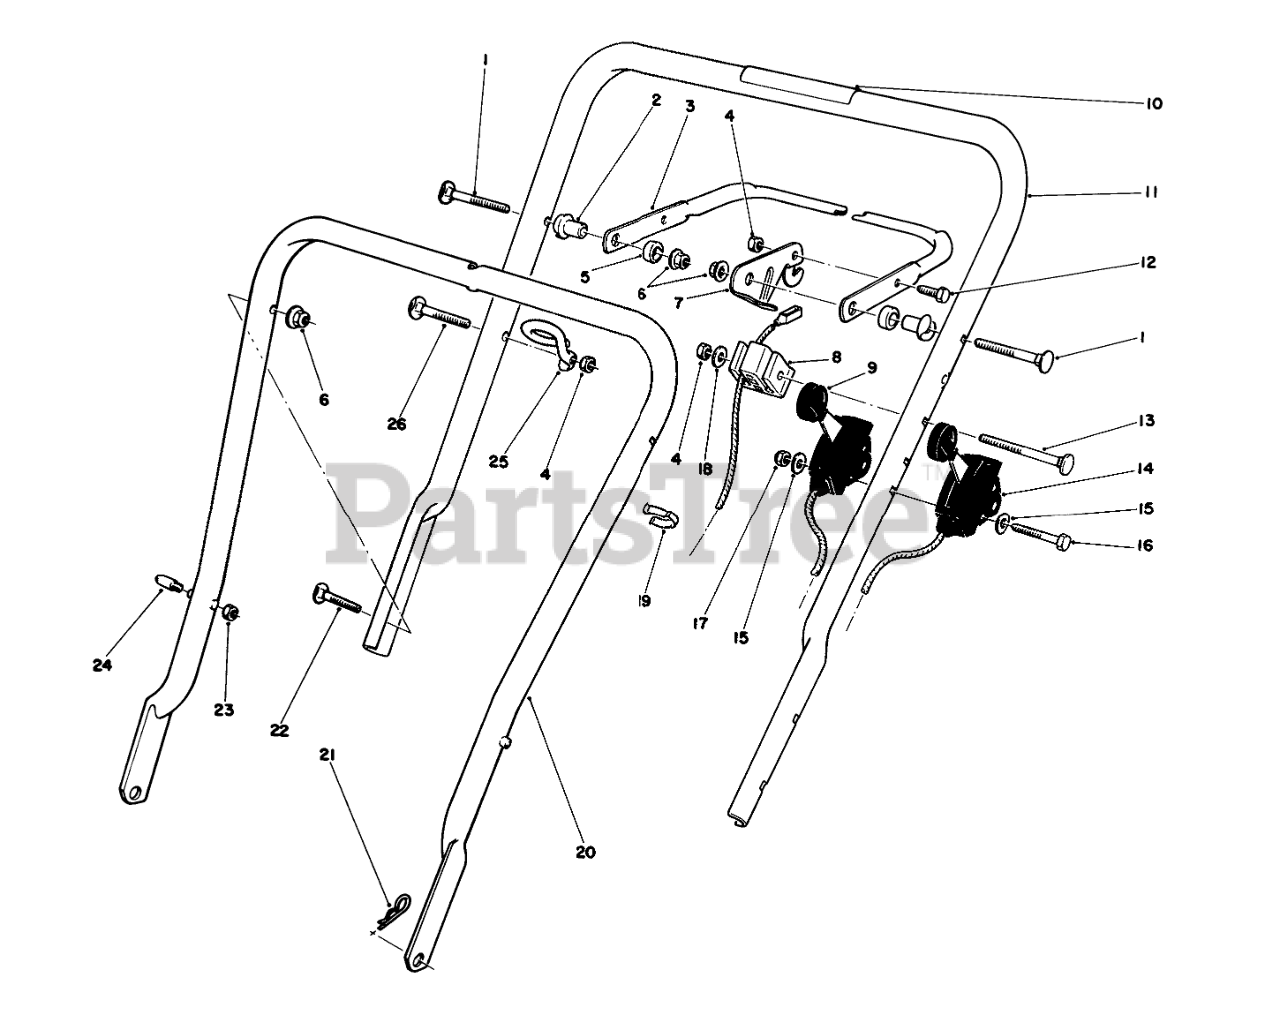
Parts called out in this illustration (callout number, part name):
1	5/16-18 X 2 HNDLE SCREW
2	SPACER-SUPPORT
3	CONTROL BAR PROMO
4	NUT-LOCK, NI
5	SPACER-NYLON
6	NUT-LOCK, NI
7	Lever-Control
8	SUPPORT-CABLE
9	THROTTLE CONT-SERVICE
10	Decal-Danger
10	WARNING DECAL
11	Handle-Upper (Incl. Ref. #10)
12	SCREW-HH
13	HANDLE SCREW
14	SERVICE TRACT. CONTROL
15	WASHER-FLAT
16	Capscrew
17	NUT-LOCK, NI
18	WASHER-FLAT
19	BOWDEN CLIP
20	LOWER HANDLE ASM
21	PIN-COTTER, HAIR
22	SCREW
23	NUT-LOCK, NI
24	HANDLE PIN
25	Guide
26	HANDLE SCREW
